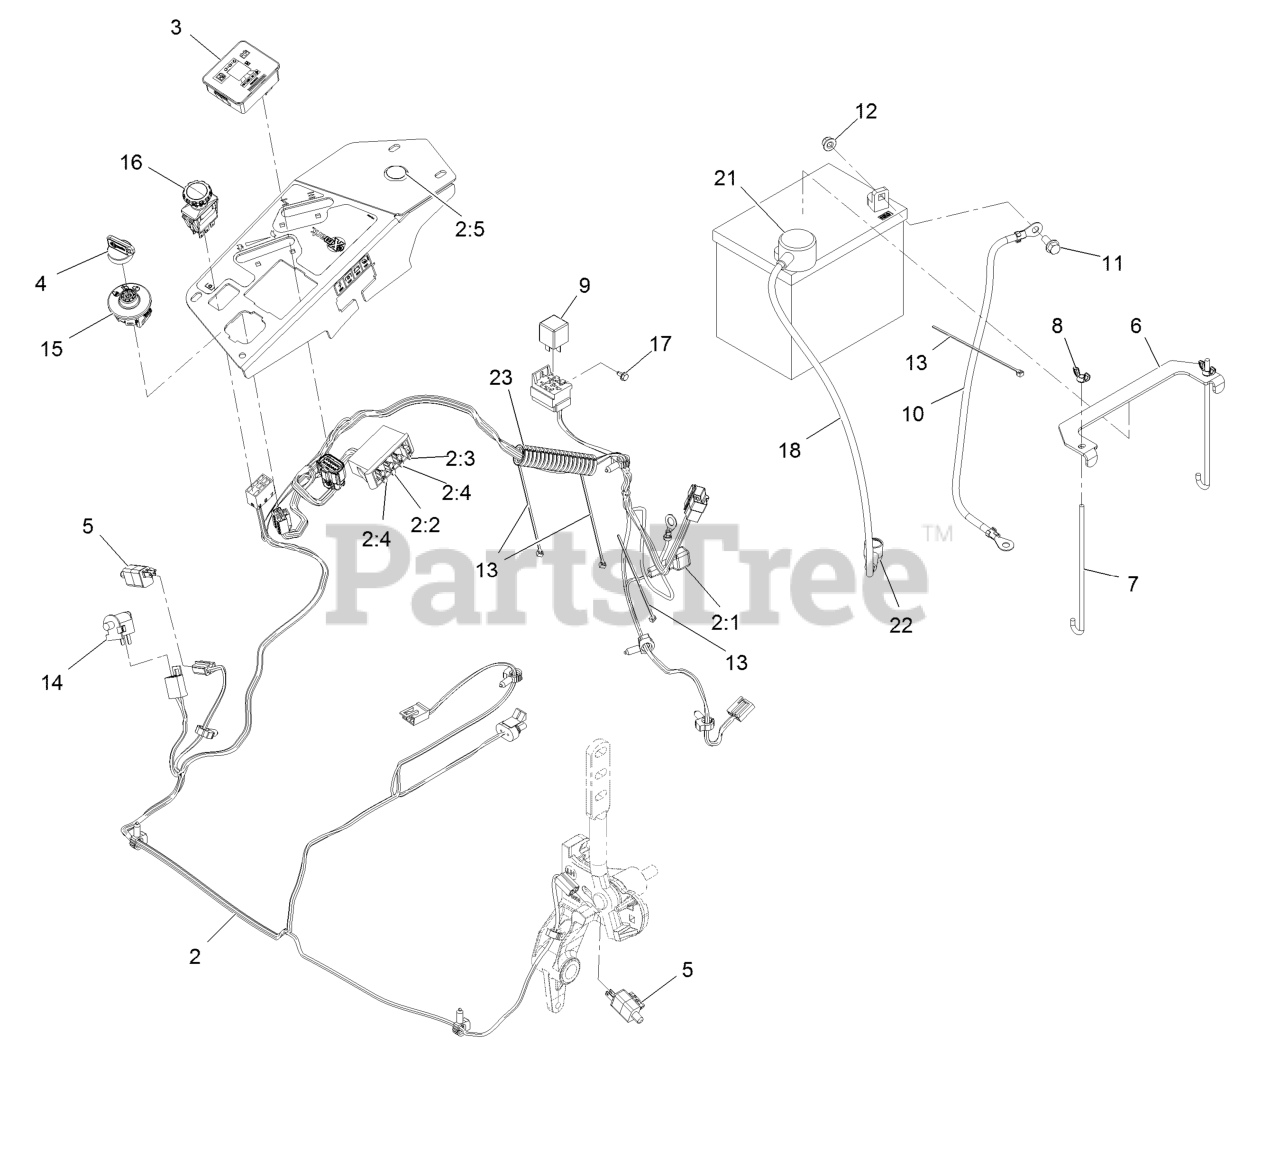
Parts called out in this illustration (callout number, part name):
2	Harness-Wire, Main
2:2	Fuse-Blade, 10 Amp
2:3	Fuse-Blade, 15 Amp
2:4	Fuse-Blade, 25 Amp
2:5	Cap-Plug
3	Fuel/Hour Meter ASM
4	Key-Ignition
4	Key-Exmark Logo
6	Strap-Tie Down, Battery
7	Bolt-Holddown
8	Wingnut-Nyloc 1/4-20
9	Relay-12Vdc 40 Amp
10	Cable-Battery, Negative
11	Screw-HH Flg 5/16-18 X 3/4
12	Nut-Nyloc 5/16-18 Flg
13	Tie-Cable 5 1/2 (Small)
15	Switch-Ignition
16	Switch-PTO, 10 Amp
17	Screw-HWH #10-24 X 3/8
18	Cable-Battery, Positive
21	Insulator-Battery
22	Insulator-Solenoid
23	Cover-Hose
